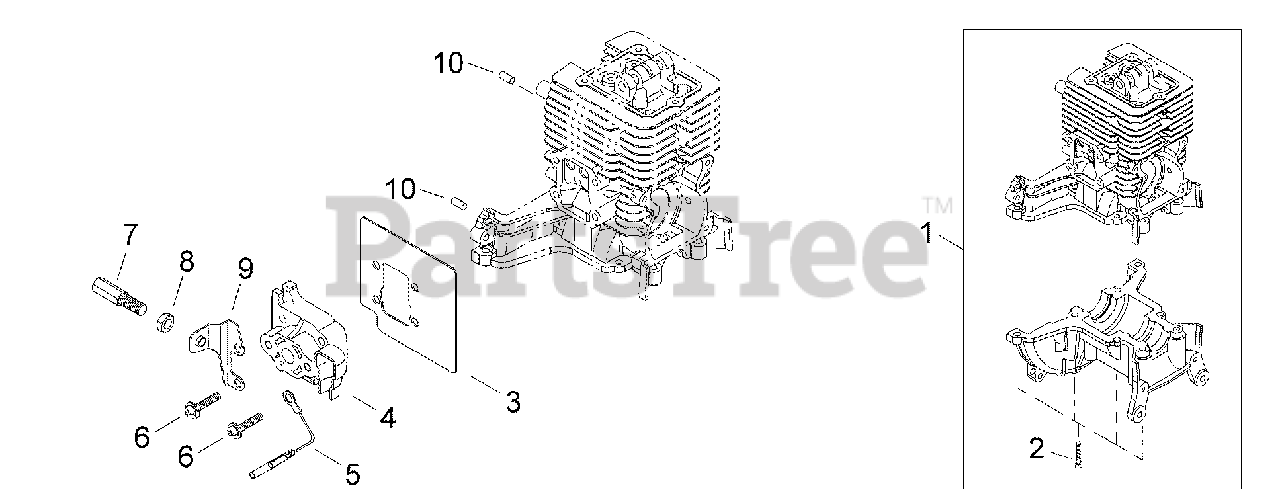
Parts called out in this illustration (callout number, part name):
1	CYLINDER BLOCK SET
2	SCREW - 5X16
3	DEFLECTOR, HEAT
4	VALVE, REED
5	LEAD - GROUND
6	SCREW - 5X25
7	NUT, CABLE ADJUST
8	LOCKNUT - 6
9	BRACKET, THROTTLE CABLE
10	PIN - LOCATING
